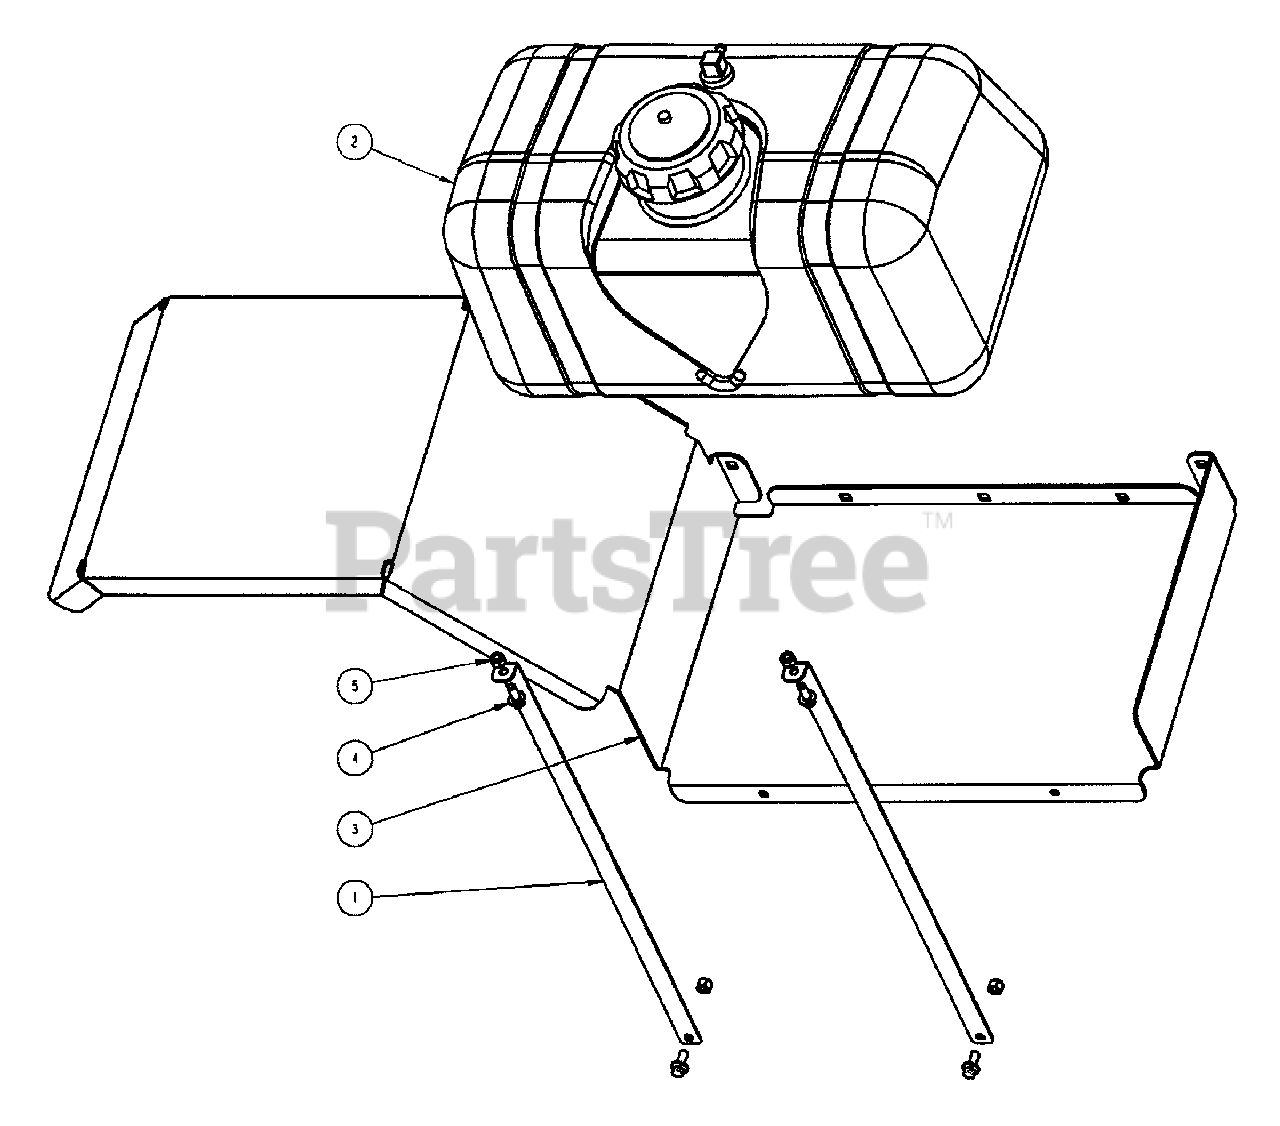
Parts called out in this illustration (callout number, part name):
1	STRAP, GAS TANK
2	FUEL TANK
3	BRKT.,GAS TANK
4	HFLB, 1/4-20 X 5/8
5	1/4-20 HEX NYLON INSERT NUT
